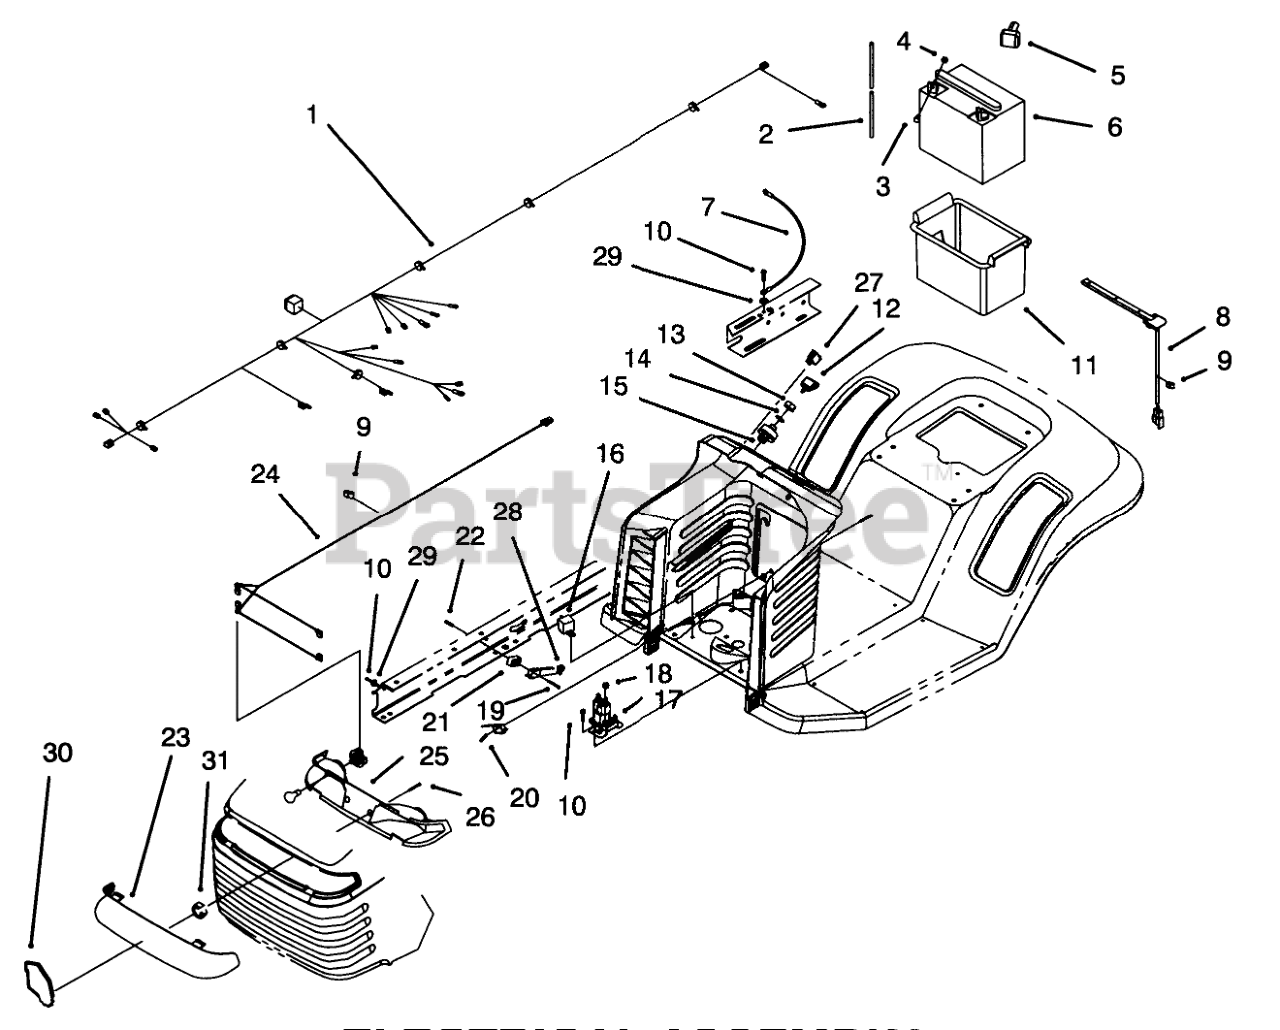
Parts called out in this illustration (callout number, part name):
1	Harness-Wire
2	TUBE-BATT DRAIN/80-2600
3	SCREW-HH
4	NUT-WING
5	BOOT-TERMINAL
6	Battery
7	WIRE ASM
8	SWITCH-SEAT
9	CLIP-RETAINER, WIRE
10	SCREW-HWH
11	BOX-BATTERY
12	KEY-IGNITION
13	NUT-HH
14	WASHER-TOOTH, INTERNAL
15	Switch-Ignition (Incl. Ref. #13 & 14)
16	RELAY
17	Solenoid
18	NUT-KEPS
19	Screw
20	SWITCH-MICRO
21	SPACER
22	NUT-SPEED
23	LENS-HEADLIGHT
24	HARNESS-WIRE, LIGHTS
25	HEADLIGHT REFLECTOR ASM
27	SWITCH-ROCKER
28	PLUNGER-SEAL
29	WASHER-LOCK/EXT
30	EMBLEM-GRILLE WHEELHORSE
